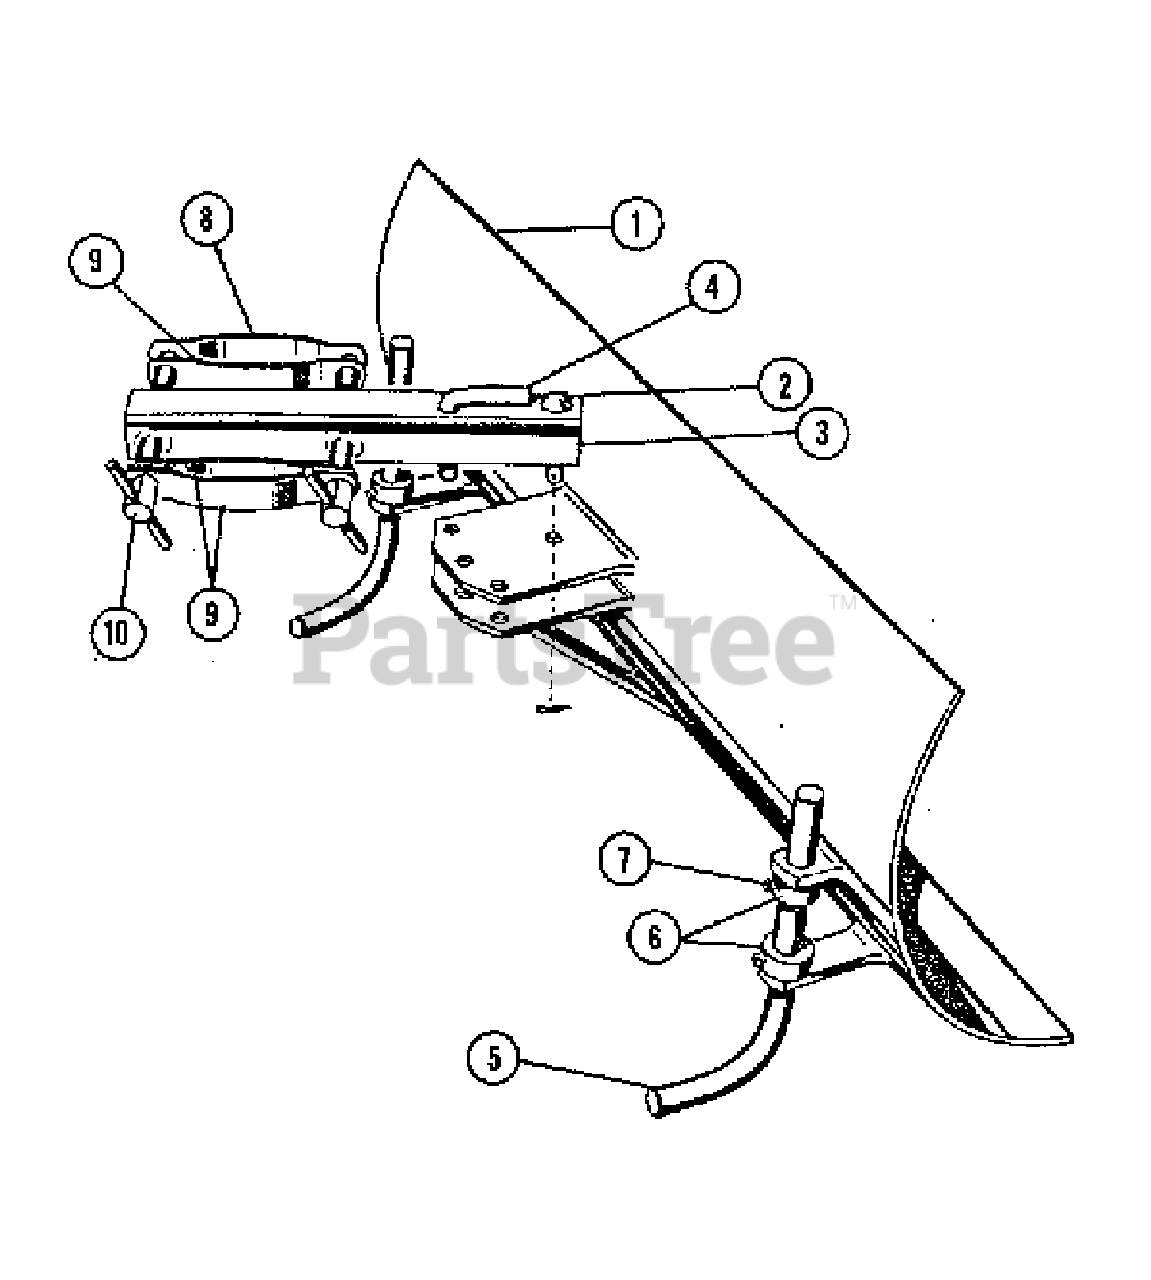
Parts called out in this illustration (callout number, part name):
1	BLADE ASSEMBLY
3	BAR ASSSEMBLY, Push
6	COLLAR, Set
7	SCREW, Set
8	CLAMP, Hitch
9	SIDE PLATE, Hitch
10	WING NUT, Complete
